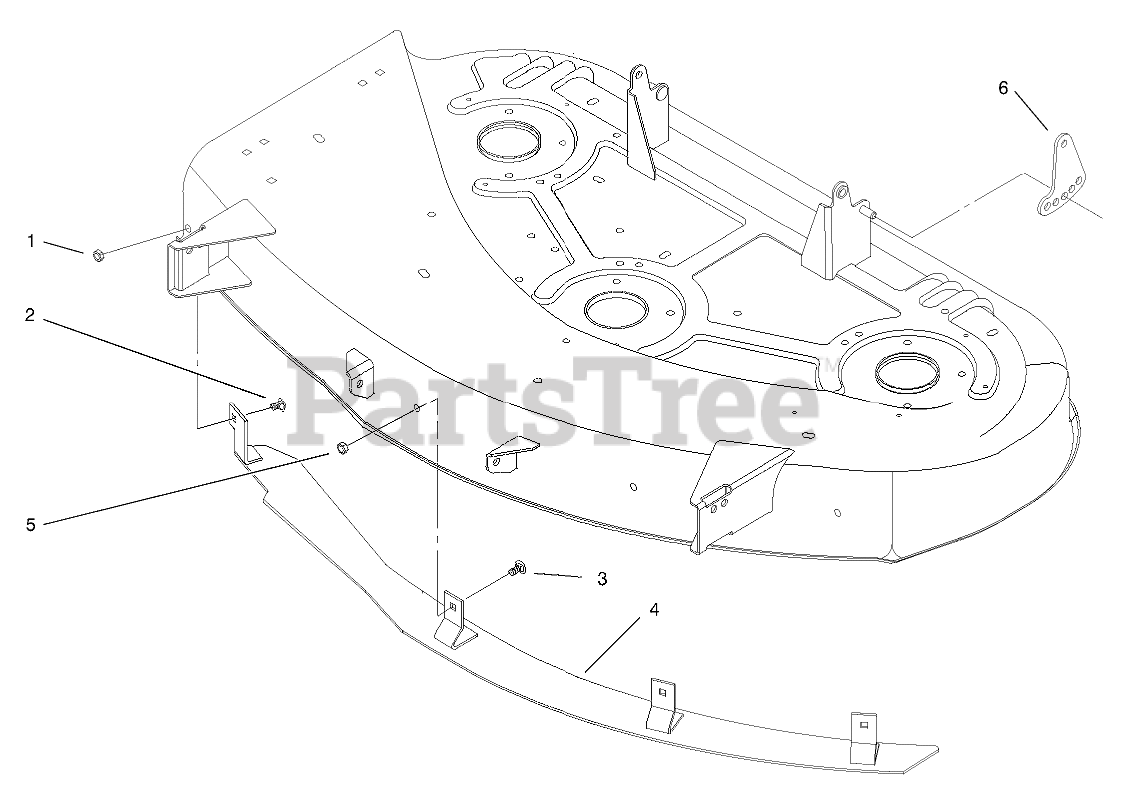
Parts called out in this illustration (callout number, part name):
1	NUT-LOCK, NI
2	SCREW-CARR
3	SCREW-CARR
5	NUT-LOCK, NI
6	LINK-ADJUSTING, HOC
